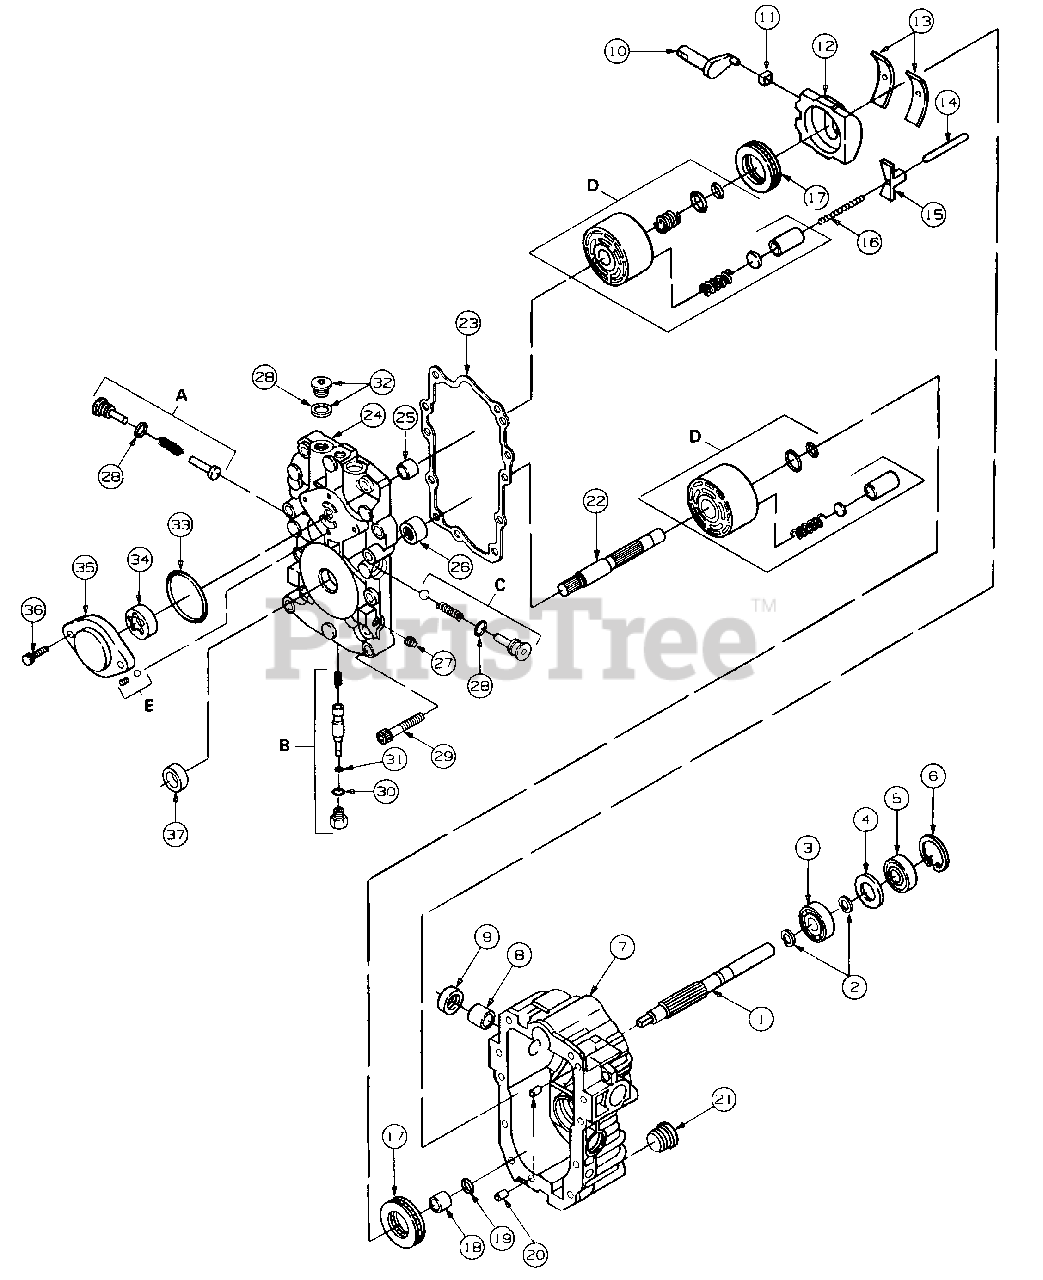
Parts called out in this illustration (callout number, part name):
1	Shaft, Pump
2	Ring, Retaining
3	Bearing, Ball
4	Spacer
5	Seal, Lip
6	Ring, Retaining
7	Housing Assy
8	Bearing, Journal
9	Seal, Lip
10	Arm, Trunnion
11	Guide, Slot
13	Bearing, Cradle
15	Leveler, Swashplate
16	Spring, Leveler
17	Bearing, Thrust
18	Bearing, Journal
19	Washer, Thrust
22	Shaft, Motor
23	Gasket, Center Section
24	Center Section Assy (Includes Ref No. 25 & 26)
25	Bearing, Journal
26	Bearing, Needle
28	O-Ring
29	Screw, Socket Hd
30	O-Ring
31	O-Ring
33	O-Ring
34	Gerotor Assy
35	Housing, Charge Pump
36	Screw, Socket Hd
37	Seal, Lip
A	Kit, Orificed Check Valve
B	Kit, Bypass Valve
C	Kit, Check Valve
D	Kit, Cylinder Block
E	Kit, Charge Relief Valve
